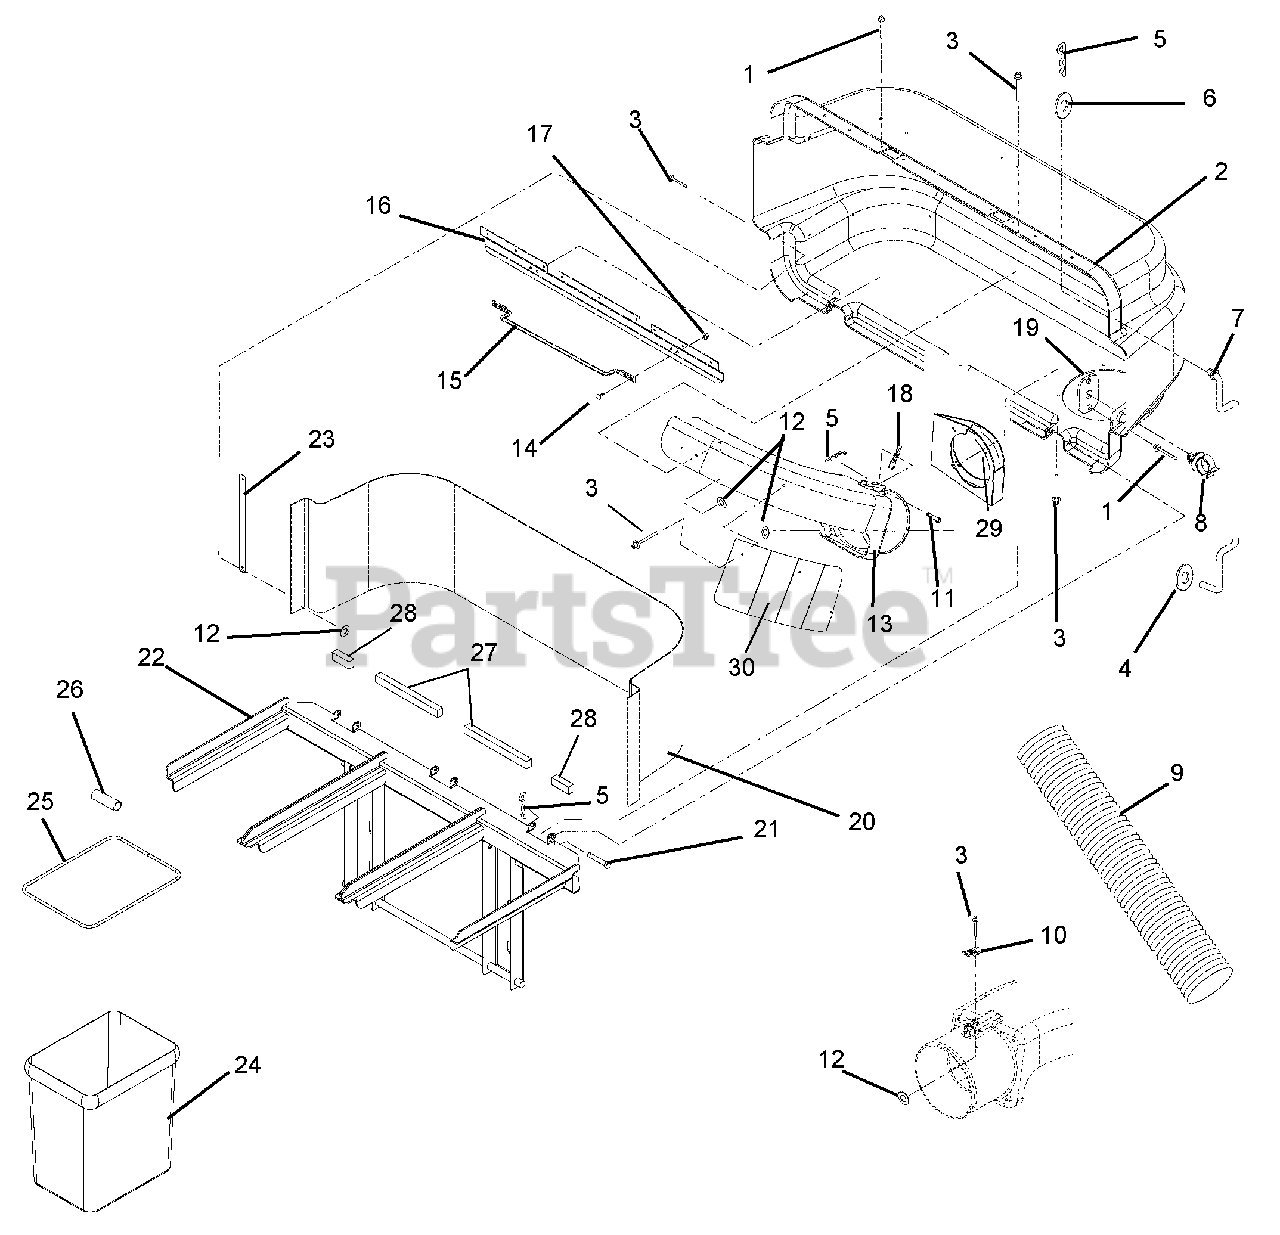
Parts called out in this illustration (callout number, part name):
1	Rivet, Pop .187 x .402
2	Cover, Bagger with Decal
3	Rivet, Pop .187 x .527 Dome Steel
4	Retainer, .38 Push-On
5	Pin-Hair
6	Washer-Flat-Steel .046 x .812 x .065
7	Prop Rod, Bagger
8	Clip .38
9	Hose, 7 x 63 Kanaflex 165 Clear
10	Thumb Latch
11	Pin, Clevis .31 x 2.62 Grade 5
12	Washer-Flat-Steel .219 x .50 x .049
13	Boot, Upper
14	Bolt, Round Head Square Neck .25-20 x .75 Grade 5
15	Bagger Handle
16	Latch, Cover
17	Nut, Locking-Top-Flange .25-20
18	Indicator, Flow
19	Plate, Rod Clip
20	Screen, Bagger
21	Pin, Clevis .368/.373 x 3.25
22	Weldment, Bagger Frame
23	Strap, Cover
24	Bag, Mesh
25	Frame, Bag
26	Hose, .38 x .50 x 3.00 Vinyl
27	Grass Block, 10.5-In. Foam
28	Grass Block, 4-In. Foam
29	Hose Support Insert
30	HD Bagger Deflector
